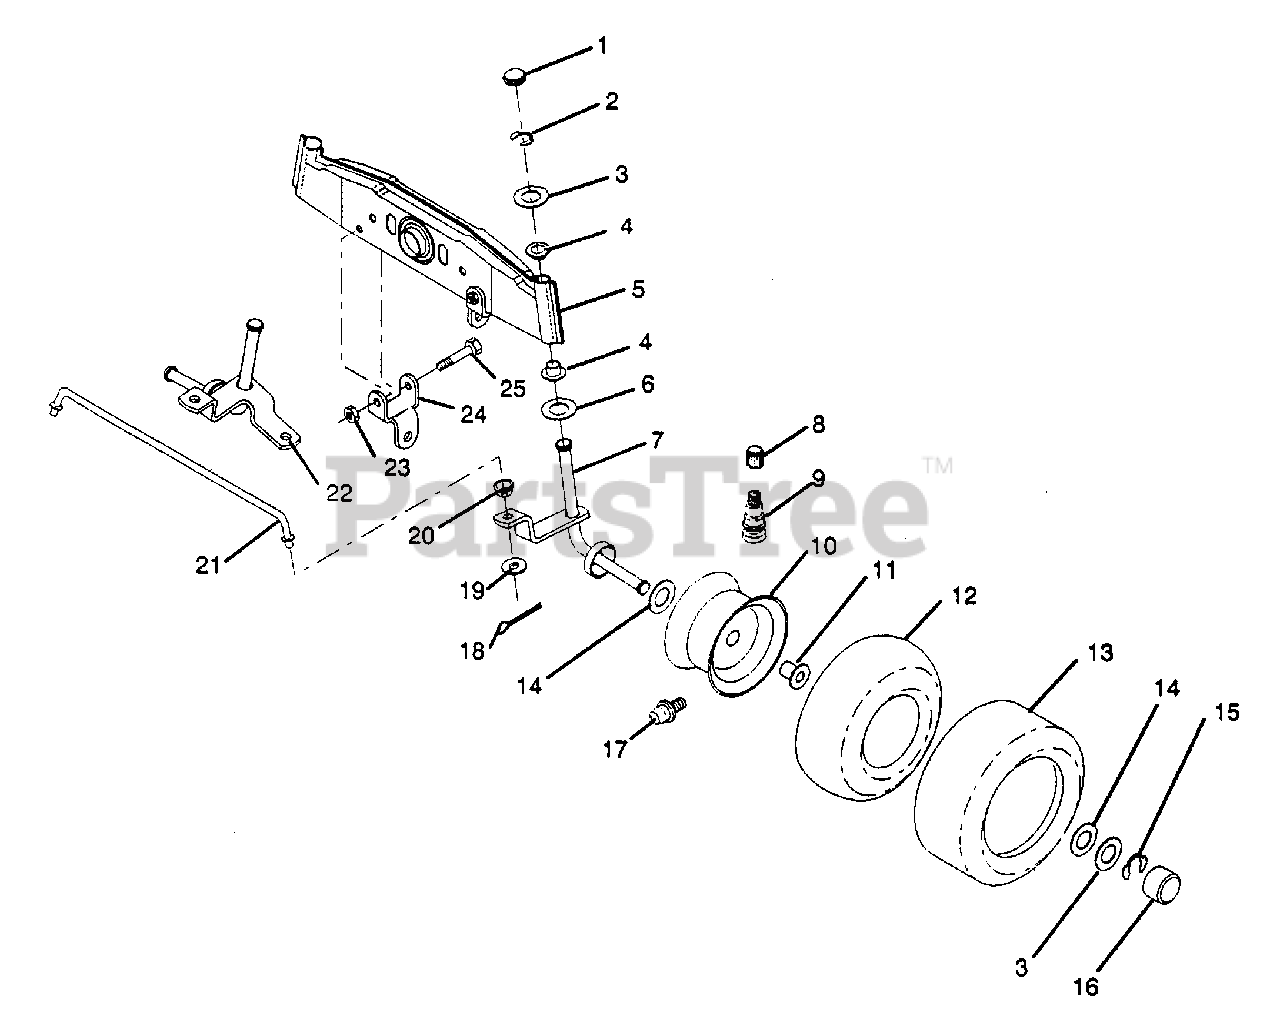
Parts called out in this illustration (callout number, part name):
1	Cap, Spindle (AYP part number)
2	Ring, Clip (AYP part number)
3	Washer 25/32 x 1-5/8 x 16 Ga. (AYP part number)
4	Nyliner (AYP part number)
5	Axle, Front (AYP part number)
6	Bearing, Thrust (AYP part number)
7	Spindle R.H. Asm. (AYP part number)
8	Cap, Valve (AYP part number)
9	Stem, Valve (AYP part number)
10	Rim (AYP part number)
11	Bearing, Flange (AYP part number)
13	Tire, Front (AYP part number)
14	Washer 25/32 x 1-1/4 x 16 Ga. (AYP part number)
15	Ring, Clip (AYP part number)
16	Cap, Hub (AYP part number)
17	Fitting, Grease (AYP part number)
18	Pin, Cotter 1/8 x 3/4 (AYP part number)
19	Washer 13/32 x 13/16 x 16 Ga. (AYP part number)
20	Bushing (AYP part number)
21	Rod, Tie (AYP part number)
22	Spindle, L.H. Asm. (AYP part number)
23	Nut, Crownlock 5/16-18
24	Bracket, Front Stabilizer Link (AYP part number)
25	Bolt, Hex, Fin. 5/16-18 UNC x 2-1/2 (AYP part number)
